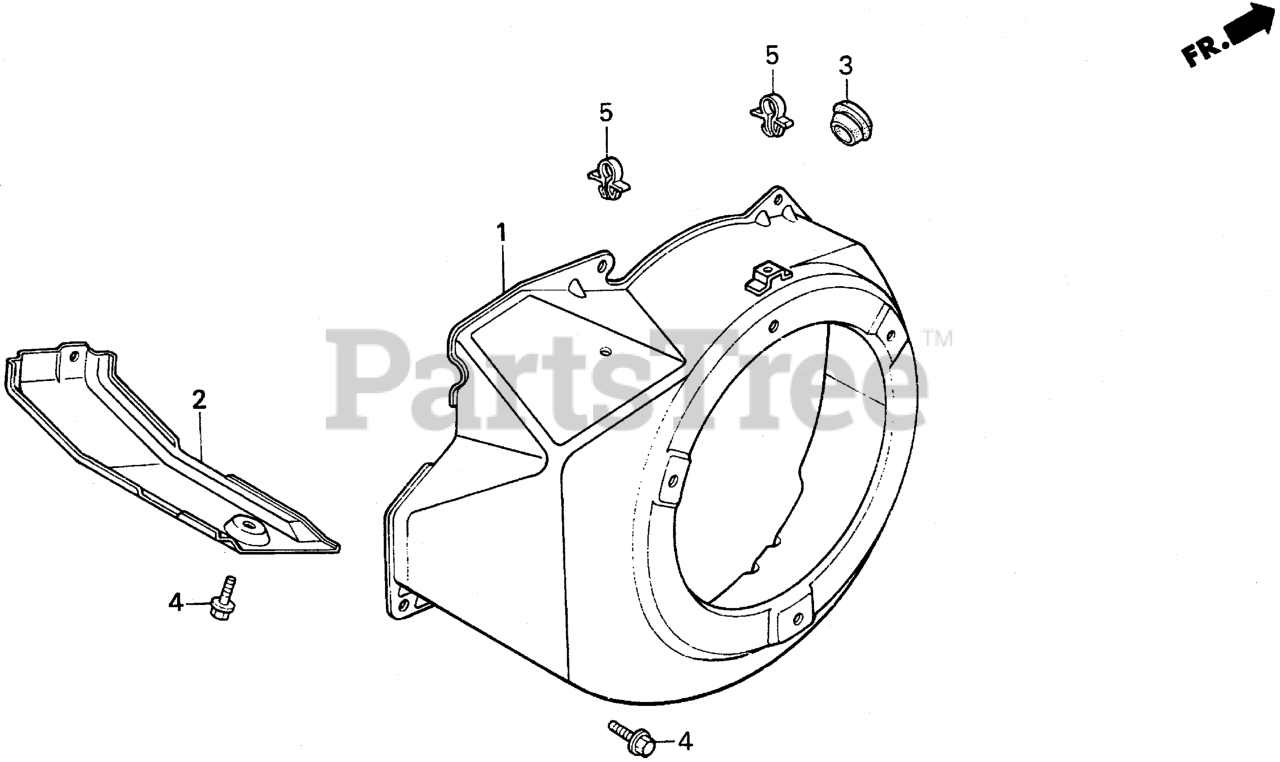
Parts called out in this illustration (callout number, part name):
1	COVER, FAN *R280* (POWER RED)
2	SHROUD
3	GROMMET, DRAIN HOLE
4	BOLT, FLANGE (6X12) (CT200)
5	CLIP, WIRE HARNESS (6MM) (WHITE)
